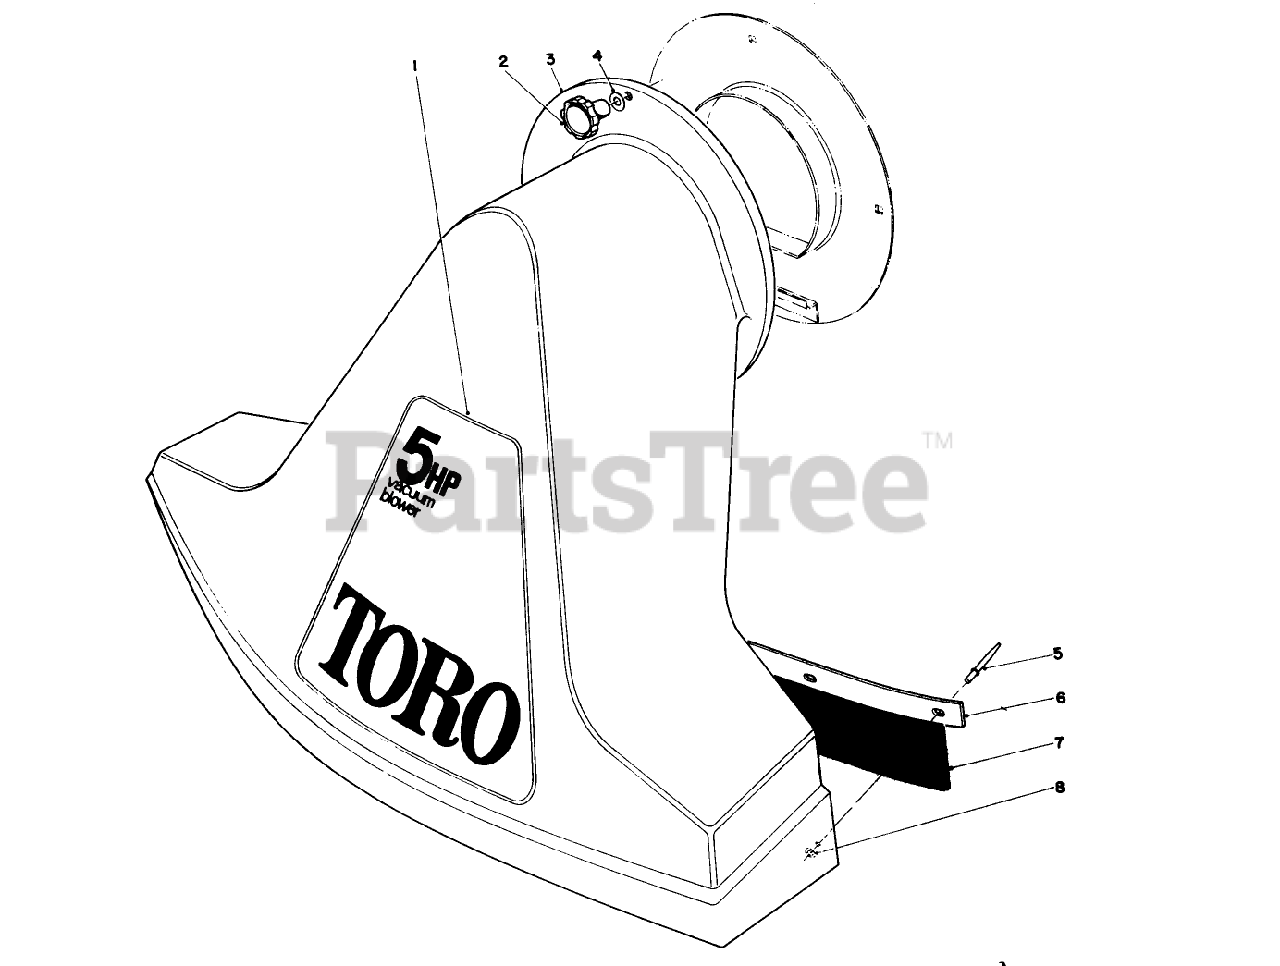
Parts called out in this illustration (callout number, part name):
3	SNOUT ASM
5	POP RIVET 3/16X.375LG
7	FLAP-RUBBER
8	WASHER-FLAT
